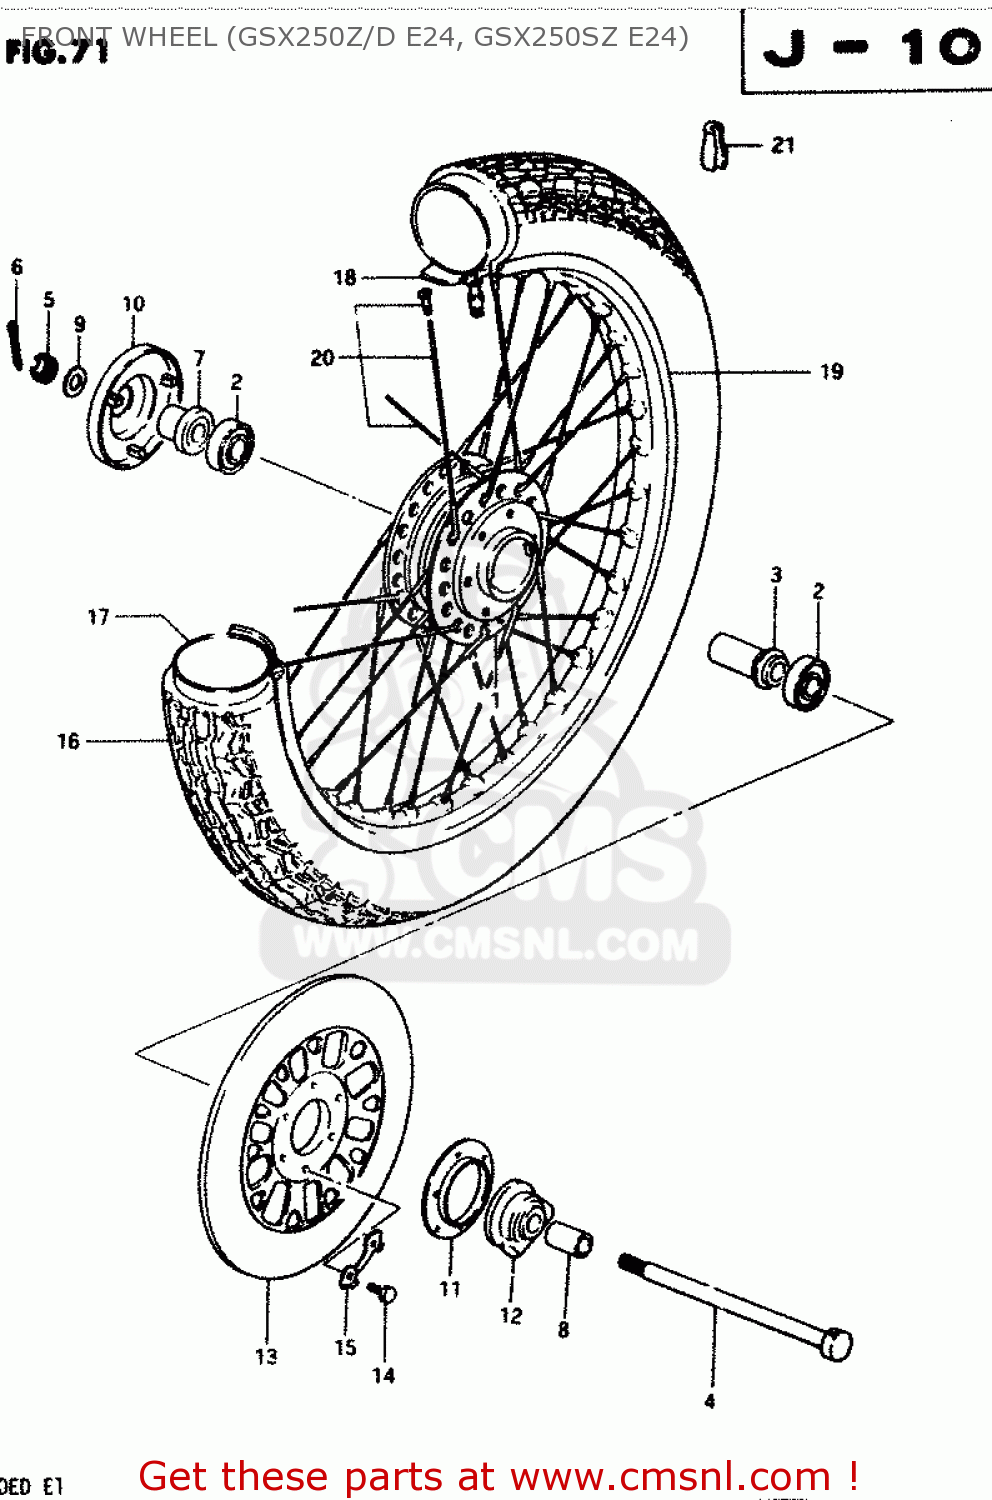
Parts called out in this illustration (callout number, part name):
1	DRUM,FRONT HUB
2	BEARING
3	SPACER,FR HUB BEARING
4	AXLE,FRONT
5	NUT 12MM
6	COTTER PIN
7	SPACER,FR HUB BEARING,R
8	SPACER(15X22X30)
9	WASHER
10	COVER,FR HUB,R
11	DUST SEAL,SPEEDOMETER GEAR BOX
12	BOX ASSY,SPEEDOMETER GEAR
13	DISC,FR BRAKE
14	BOLT(8X25)
15	WASHER
16	TIRE,FRONT
17	TUBE,INNER
18	PROTECTOR,INNER TUBE
19	RIM,FR WHEEL
20	SPOKE ASSY,FR WHEEL
21	BALANCER,WHEEL (B)
